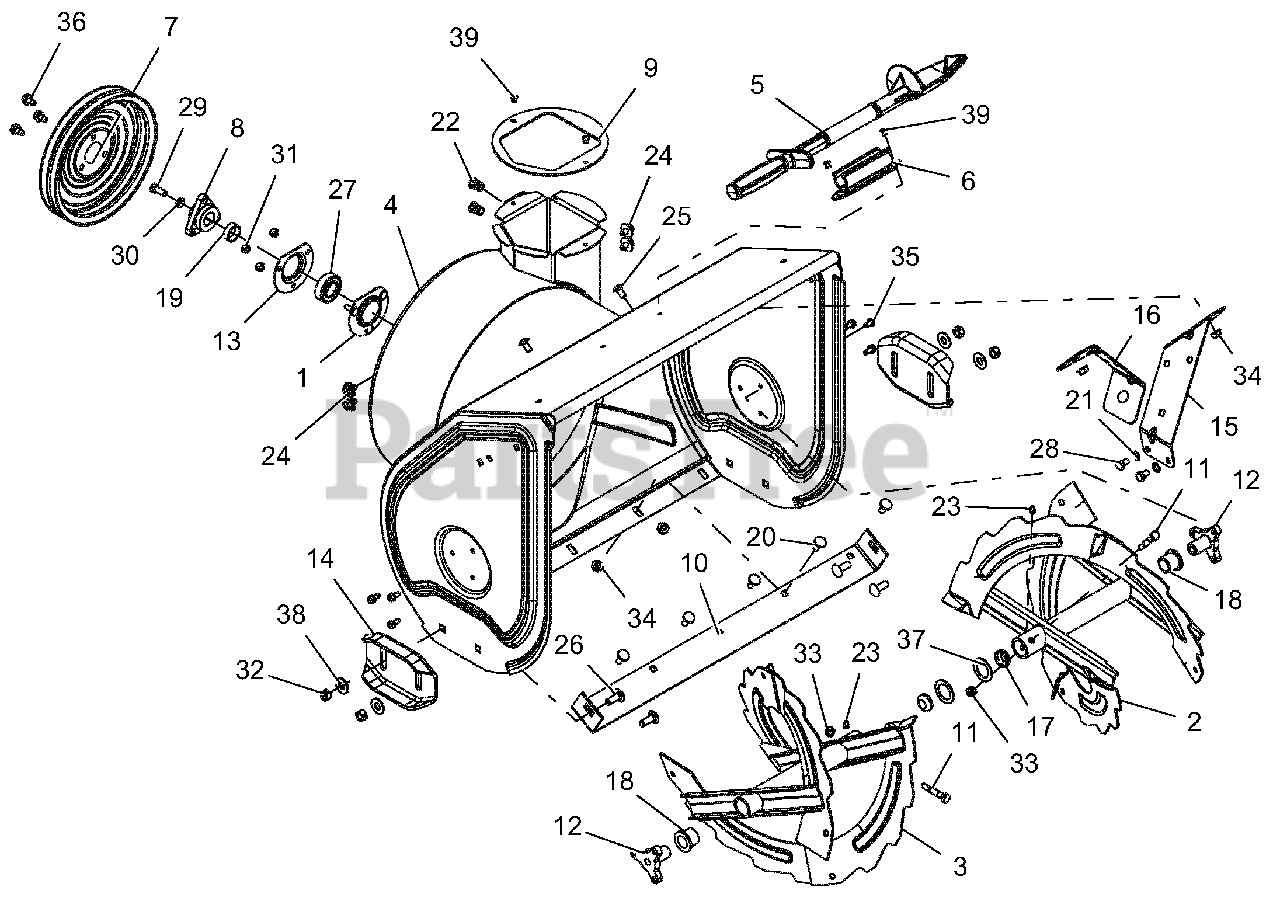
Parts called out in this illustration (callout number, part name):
1	BEARING FLANGE
2	RAKE, LEFT HAND-24" DELUXE
3	RAKE, RIGHT HAND-24" DELUXE
4	HOUSING, BLOWER - 24" DELUXE
5	DEVICE, SNOW CLEAN OUT
6	MOUNT, SNOW CLEAN OUT
7	PULLEY, SPIN FORM DUAL GROOVE
8	PULLEY HUB, D-BORE .87 DELUXE
9	BAFFLE, DISCHARGE NECK
10	BLADE, SCRAPER-24"
11	SHEAR BOLT SERVICE ASSEMBLY
12	SUPPORT, RAKE BUSHING
13	BEARING FLANGE
14	SKID SHOE, REVERSIBLE - ORANGE
15	BRACKET, GEARCASE SUPPORT - LH
16	BRACKET, GEARCASE SUPPORT - RH
17	PLUG, RAKE TUBE
18	BSHG-FLG, NY.778 ID X 1.018 OD
19	BSHG-SPCR .895IDX1.065ODX.353
20	BOLT, MODIFIED HEAD CARRIAGE
21	@WSHR-LK-EXT.326X.599X.031YWZC
22	NUT, THREADED INSERT .38-16
23	ZERK,FITTING .25X.125 DRIVE IN
24	SCR-TAP.31-18X.50 HWH TR YWZ
25	BLT-RDHDSQSHNK.31-18X.62 YZ-LK
26	@BLT-RDHDSHSQNK.38-16X1.0 G5YZ
27	BRG-BALL .876 X 1.750 X .50
28	@BLT-HEX .31-18X.50 GR5 YWZC
29	BLT-HEX .31-24X.75 YWZC GR5
30	WSHR-LK .312X.097 HVY YWZC
31	@NUT-LK-CTR .25-20 YWZC
32	@NUT-LK-CTR .38-16 YWZC
33	NUT-LK-CTR .31-18 YWZC
34	@NUT-LK-TOP-FLG .31-18 YWZC
35	SCR-TAP .25-20X.50 HWH TR YWZ
36	@SCR-TAP .31-18X.50 HWH TR YWZ
37	WSHR-FL-STL 1.010X1.505X.062YZ
38	@WSHR-FL-STL.438X1.00X.083 YWZ
39	RVT-POP .187 YZ
